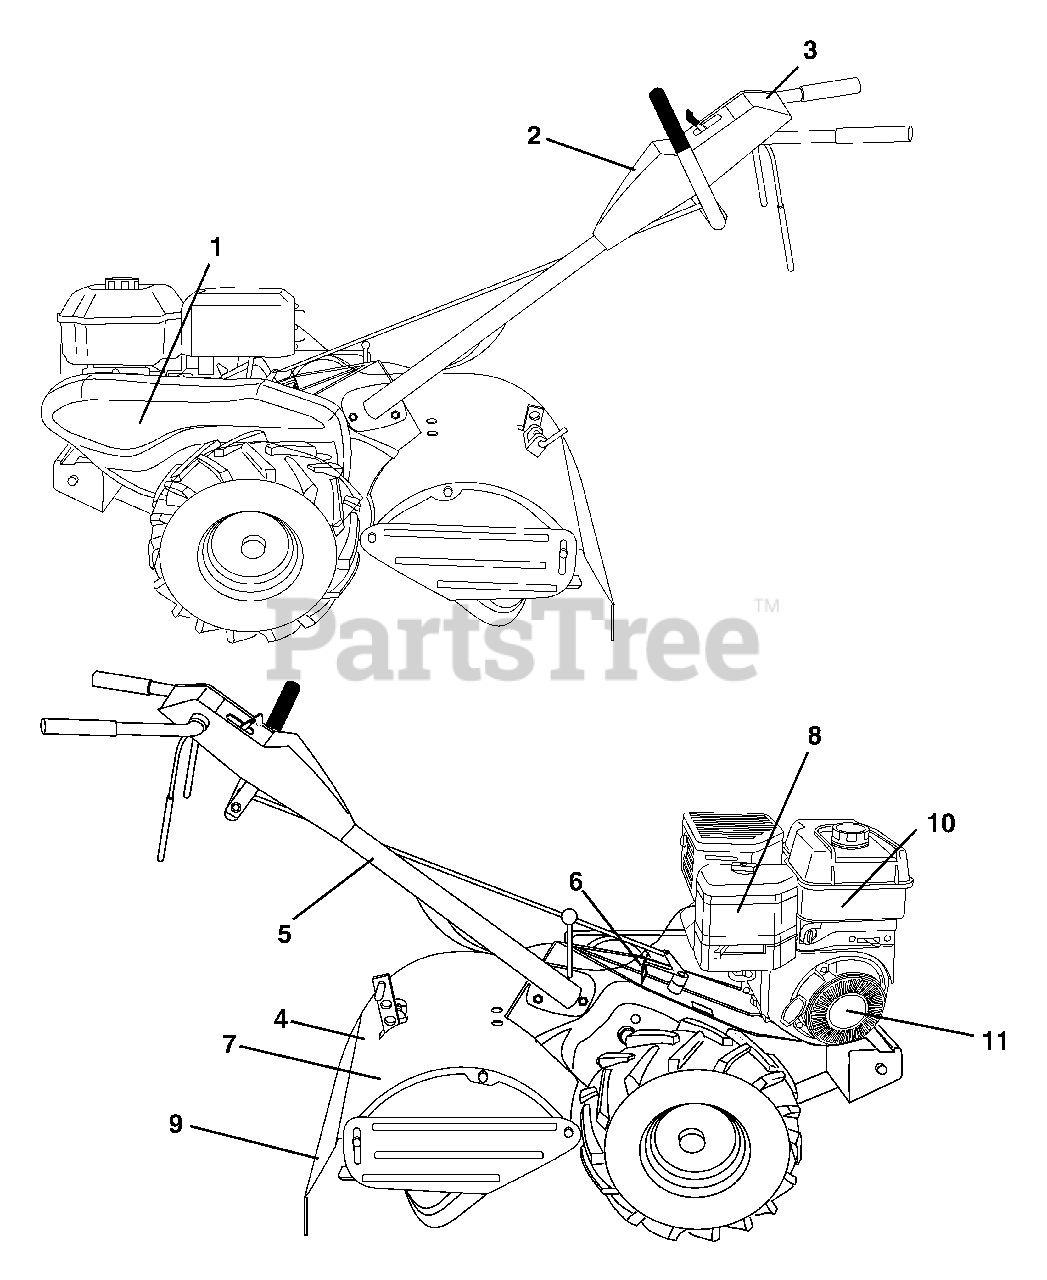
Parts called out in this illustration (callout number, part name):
1	Decal, Belt Guard
2	Decal, CNTRL PNL
3	Decal, Control Tine
4	Decal, Tine Shield
5	Decal, Hand Placement
6	Decal, Shift Indicator
7	Decal, Warning
8	Decal, Engine B&S
9	Decal, Warning, Rotating Tines
10	Decal, Engine Intek REF
11	Decal, Rewind Intek #274350
